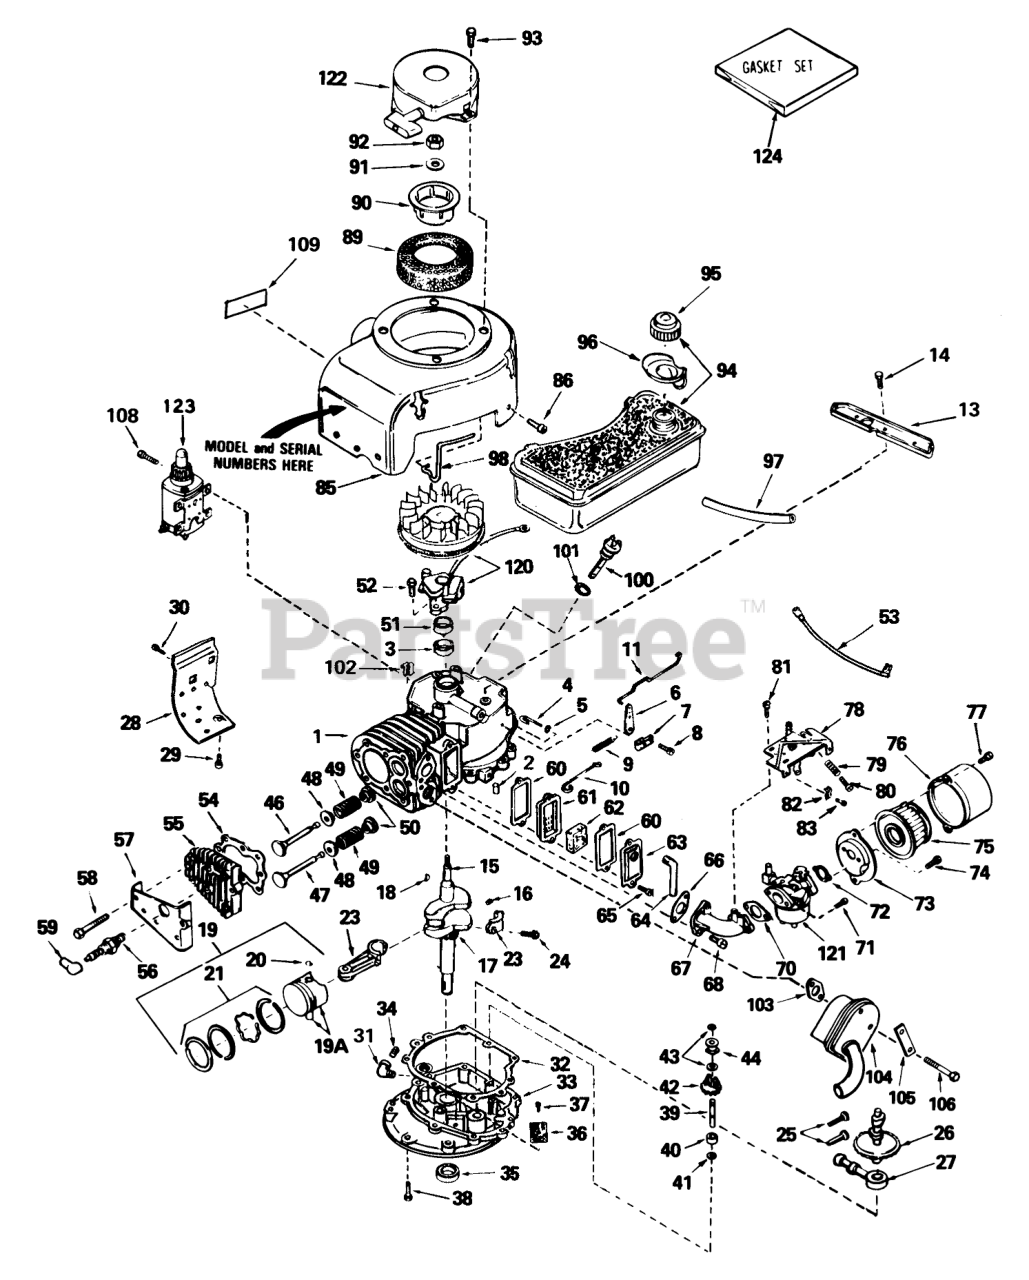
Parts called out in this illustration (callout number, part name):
1	Cylinder Assy. (Incl. Ref. #2, 3, 100 & 101)
2	Pin-Dowel
3	Oil Seal
4	Rod, Governor (Incl. Ref. #5)
5	Washer-Flat
6	Lever-Governor
7	Clamp-Lever, Governor
8	Screw
9	Spring Governor
10	Link Governor Spring
11	Link Governor
13	Bracket-Blower Housing
14	Screw (1/4-20x19/32)
15	Crankshaft Assembly (Incl. Ref. #16 & 17)
16	Pin, Groove
17	Gear-Crankshaft
18	Key-Flywheel
19	Piston, Pin & Ring Assy. (Std.) (Incl. Ref. #19A, 20 & 21)
19	Piston, Pin & Ring Assy. (.010 oversize) (Incl. Ref. #19A, 20 & 21)
19	Piston, Pin & Ring Assy. (.020 oversize) (Incl. Ref. #19A, 20 & 21)
19A	Piston & Pin Assy. (Std.) (Incl. Ref. #20)
19A	Piston & Pin Assy. (.010 oversize) (Incl. Ref. #20)
19A	Piston & Pin Assy. (.020 oversize) (Incl. Ref. #20)
20	Ring-Retaining, Piston Pin
21	"O"Ring
21	Ring Set (.010" OS)
21	Ring Set (.020" OS)
23	Rod Assy., Connecting (Incl. Ref. #24)
24	Bolt, Connecting Rod
25	Lifter-Valve
27	Pump, Oil
28	Emnsion, Blower Housing
30	Screw
31	Elbow, 90
32	Gasket-Cover, Cylinder
33	Flange Assy., Mounting (Incl. Ref. #34 thru 37 & 39)
34	Plug-Drain, Oil (SQH 1/4-18)
35	Seal-Oil
36	Screen-Oil Filter
38	Screw (1/4-20 x 1-1/4)
39	Shaft, Governor
40	Spacer Assy. Governor (Incl. Ref. #41)
41	Washer-Flat
42	Gear Assy., Governor (Incl. Ref. #41)
43	Ring-Retaining
44	Spool-Governor
46	Valve, Intake (Std.) (Incl. Ref. #50)
46	Valve, Intake (1/32" oversize) (Incl. Ref. #50)
47	Valve, Exhaust (Std.) (Incl. Ref. #50)
47	Valve, Exhaust (1/32" oversize) (Incl. Ref. #50)
48	Cap-Spring, Valve
49	Spring-Valve
50	Keeper-Spring, Valve
51	Gasket Stator
53	SPOOL RETAINER (10-PK)
54	Gasket-Cylinder Head
55	Head, Cylinder (Incl. 3 of Ref. #58)
56	Plug, Spark (J17LM or equiv.)
56	Plug, Spark (Champion RCJ-8)
57	Cover-Head, Cylinder
58	Screw (5/16-18 X 2-1/2)
59	Cover-Spark Plug
60	Gasket-Breather
61	Body-Breather
62	Element-Breather
63	Cover-Valve
64	Tube-Breather
66	Gasket-Intake
67	Pipe-Intake
68	Screw (T-30, 5/16-18x1-3/32)
70	Gasket
71	Screw-Hex Hd.
72	Gasket
73	Bracket
74	Screw (10-32 x 1/2)
75	Element
76	Body-Air Cleaner
78	Control Assy.Speed (Incl. Ref. #79 & 80)
79	Spring-Compression
80	Screw
81	Screw (10-24 x 9/16)
82	Conduit
83	Screw (10-32 x 3/8)
85	Housing Blower
86	Screw, Hex Hd.
89	Screen, Air
90	Cup-Starter
91	Washer-Belleville
94	Tank Assy. Fuel (Incl. Ref. #95)
95	Cap-Fuel
96	Deflector-Fuel
97	Line-Fuel (8.62)
98	Clamp, Tank Holdown
100	Dipstick, Oil (Incl. Ref. #101)
101	Gasket
102	51004 GIL ROTARY TI
103	Gasket Exhaust
104	Muffler
105	Plate-Locking
106	Screw Hex Hd.
108	Screw
109	Decal, Instruction
120	Magneto(The complete magneto is not available as an assembly. The magneto number is shown for reference purposes only. Order component parts individually,as shown in parts list.)
121	Carburetor (Incl. Ref. #70)
122	Starter, Rewind
123	Tine Shaft
124	Gasket Set
